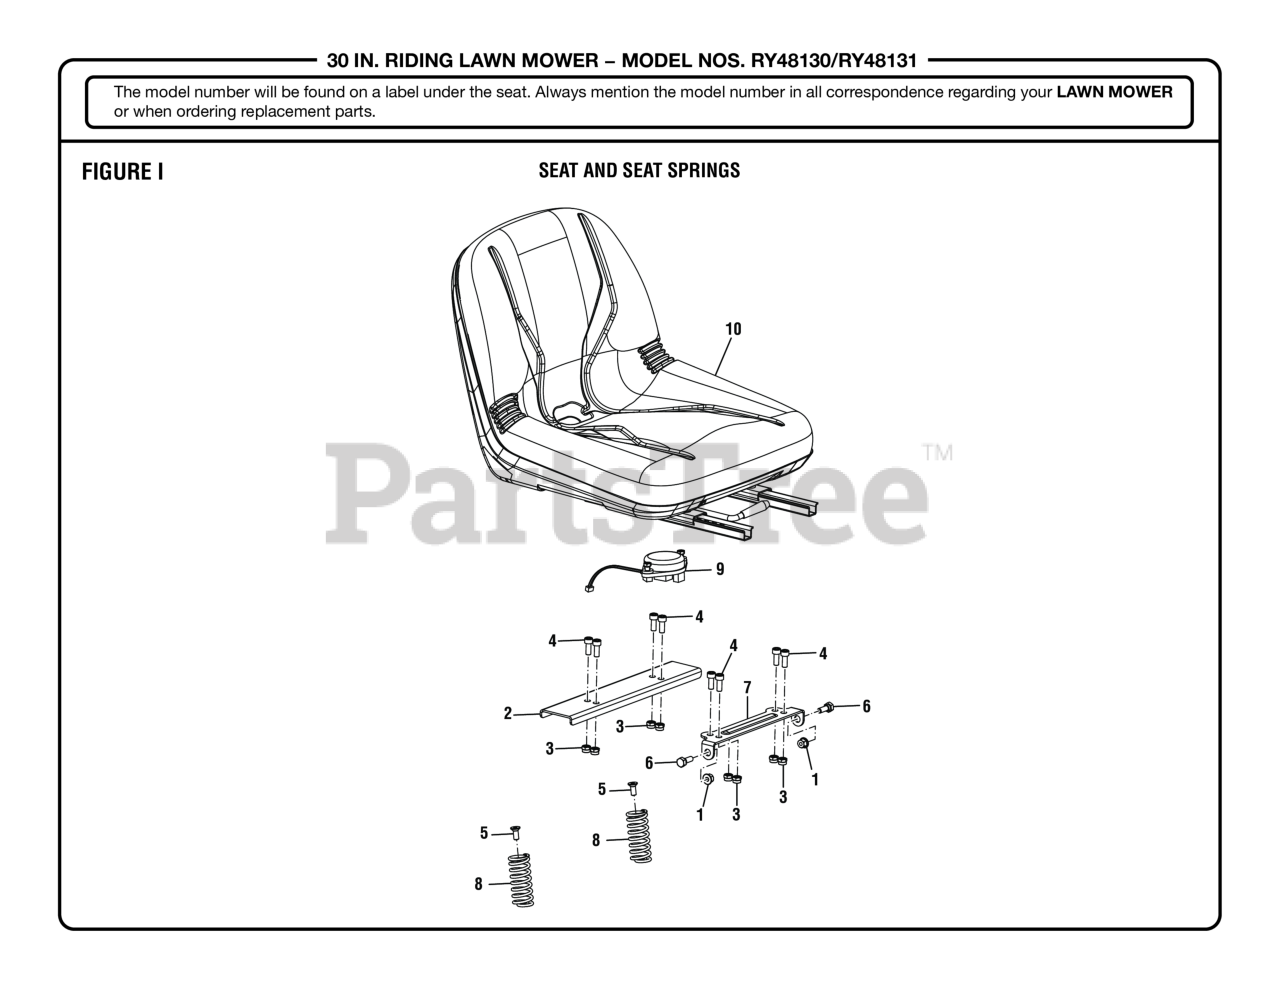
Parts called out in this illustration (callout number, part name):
1	Flange Nut (M8) (For Drive Motor Controller V)
2	Seat Base Plate, Rear
3	Lock Nut (M8)
4	Screw (M8 x 16 mm)
5	Screw (M8 x 20 mm, Hex Soc. Hd.)
6	Shoulder Bolt (M8 x 20 mm)
7	Seat Base Plate
8	Seat Spring, ZTR
9	Seat Switch
